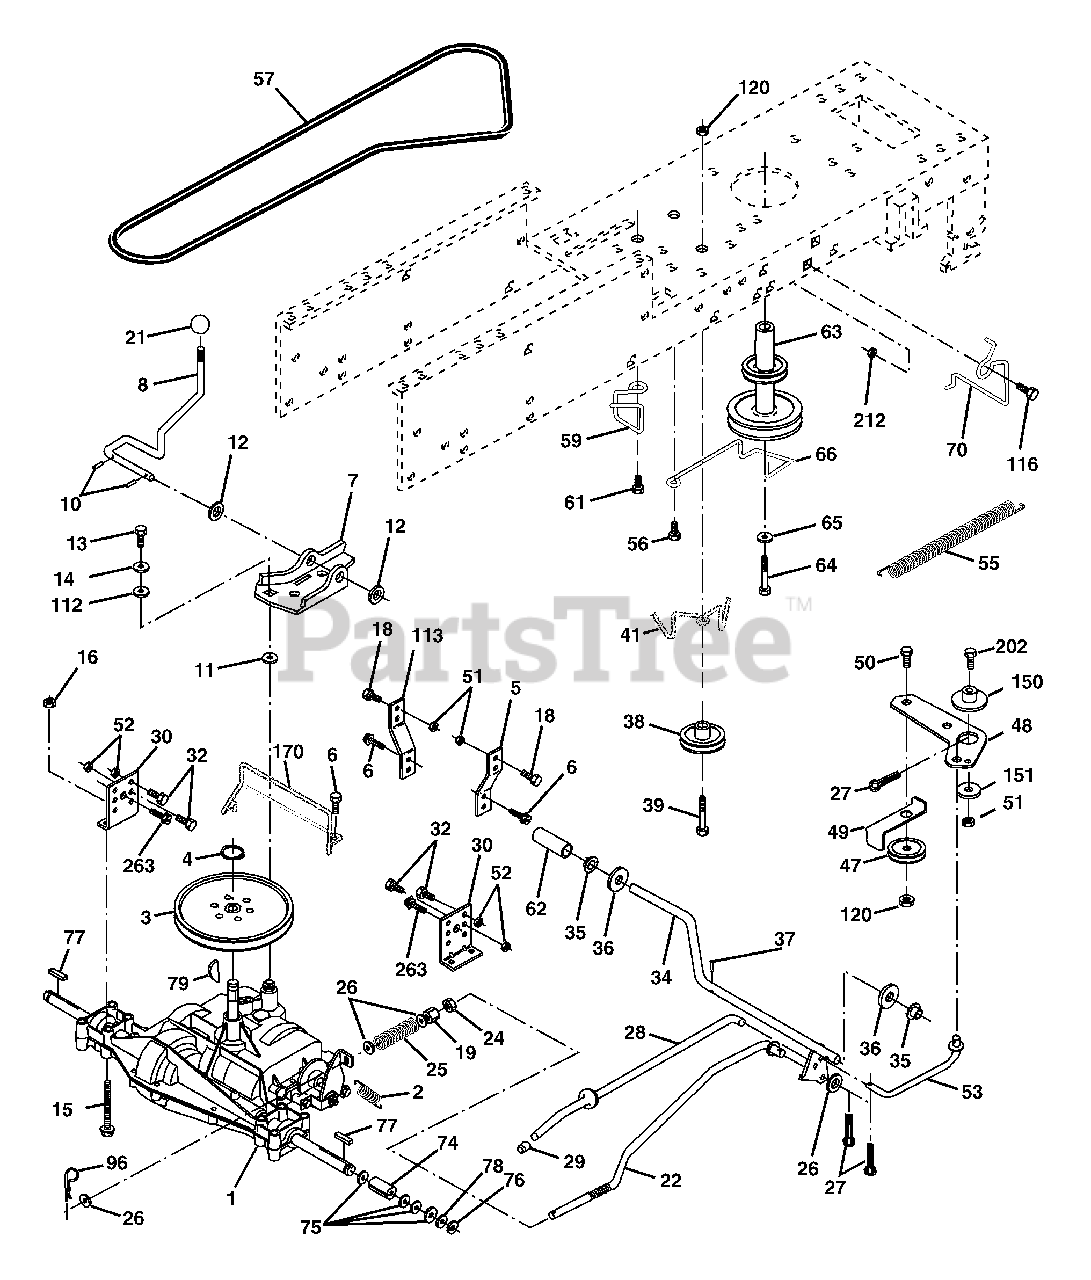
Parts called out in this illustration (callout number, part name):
2	Spring Return Brake
3	Pulley Transaxle 18" tires
4	Ring Retainer # 5100-62
5	Strap Torque 30 Degrees RH
6	Screw 5/16-18 x 3/4
7	Plate Rod Shift T/a
8	Rod Shifter Blk
10	Pin Cotter 1/8 x 1 Cad
11	Washer Plate Shf 388 Sq Hole
12	Washer 15/32 x 3/4 x 16 Ga.
13	Bolt 1/4-28 unf Gr. 8 w/Patch
14	Washer Lock Hvy Helical 1/4
15	Bolt Hex Flg.Hd. 5/16-18 x Gr.5
16	Nut Lock Hex W/Ins 5/16-18 unc
18	Bolt Fin Hex 3/8-16 unc x 1 Gr. 5
19	Nut lock Hex w/Ins 3/8-16 unc
21	Knob Rd 1/2-13 Plstc Thds Blk
22	Rod Brake LT
24	Nut Hex Jam 3/8-16 unc
25	Spring Rod Brake 2 00 Zinc
26	Washer 13/32 x 13/16 x 16 Ga.
27	Pin Cotter 1/8 x 3/4 Cad
28	Rod Brake Parking LT/YT
29	Cap Brake Parking Black
30	Bracket Transmission
32	Bolt Fin Hex 5/16-18 x 3/4
34	Shaft Asm Pedal Foot Nibbed
35	Bearing Nylon Blk 629 Id
36	Washer 21/32 x 1 x 16 Ga.
37	Pin Roll 3/16 X 1"
38	Pulley Composite Flat
39	Bolt RDHD 3/8-16 unc x 2-3/4 Gr.5
41	Keeper Belt Idler
47	Pulley Idler V Groove Plastic
48	Bellcrank Clutch Grnd Drv STL
49	Retainer Belt Style Spring
50	Bolt Carr Sh 3/8-16 x 1-1/2 Gr. 5
51	Nut Crownlock 3/8-16 unc
52	Nut Crownlock 5/16-18 unc
53	Link Clutch 7 66
55	Spring Return Clutch 6 75
56	Screw 3/8-16 x 1-1/4
57	V-Belt Ground Drive 95
59	Keeper Belt Chassis Span Ctr
61	Screw 3/8-16 x .875
62	Cover Pedal Blk Round
63	Engine Pulley LT/YT
64	Bolt Hex 7/16-20x4 Gr. 5-1.5 Thr
65	Washer Lock Hvy Hlcl Spr 7/16
66	Keeper Belt Engine
70	Guide Belt Mower Drive RH
74	Spacer Axle
75	Washer 25/32 x 1 1/4 x 16 Ga.
76	E-ring #5133-75
77	Key Square 2 0 x 1845/ 1865
78	Washer 25/32 x 1-5/8 x 16 Ga.
79	Key Woodruff
96	Retainer Spring 1"
112	Washer 9/32 x 3/4 x 10 Ga.
113	Strap Torque 90 Degrees LH
116	Bolt Rdhd Sq Neck 3/8-16 x 1
120	Nut Lock Flg 3/8-16
150	Spacer Retainer Lt
151	Washer 13/32 x 2 x 10 Ga.
170	Keeper, Belt Transaxle
202	Bolt Carr Sh 3/8-16 x 1-3/4 Gr.5
212	Nut Hex Flg Lock
263	Screw 3/8-16 x 3/4
